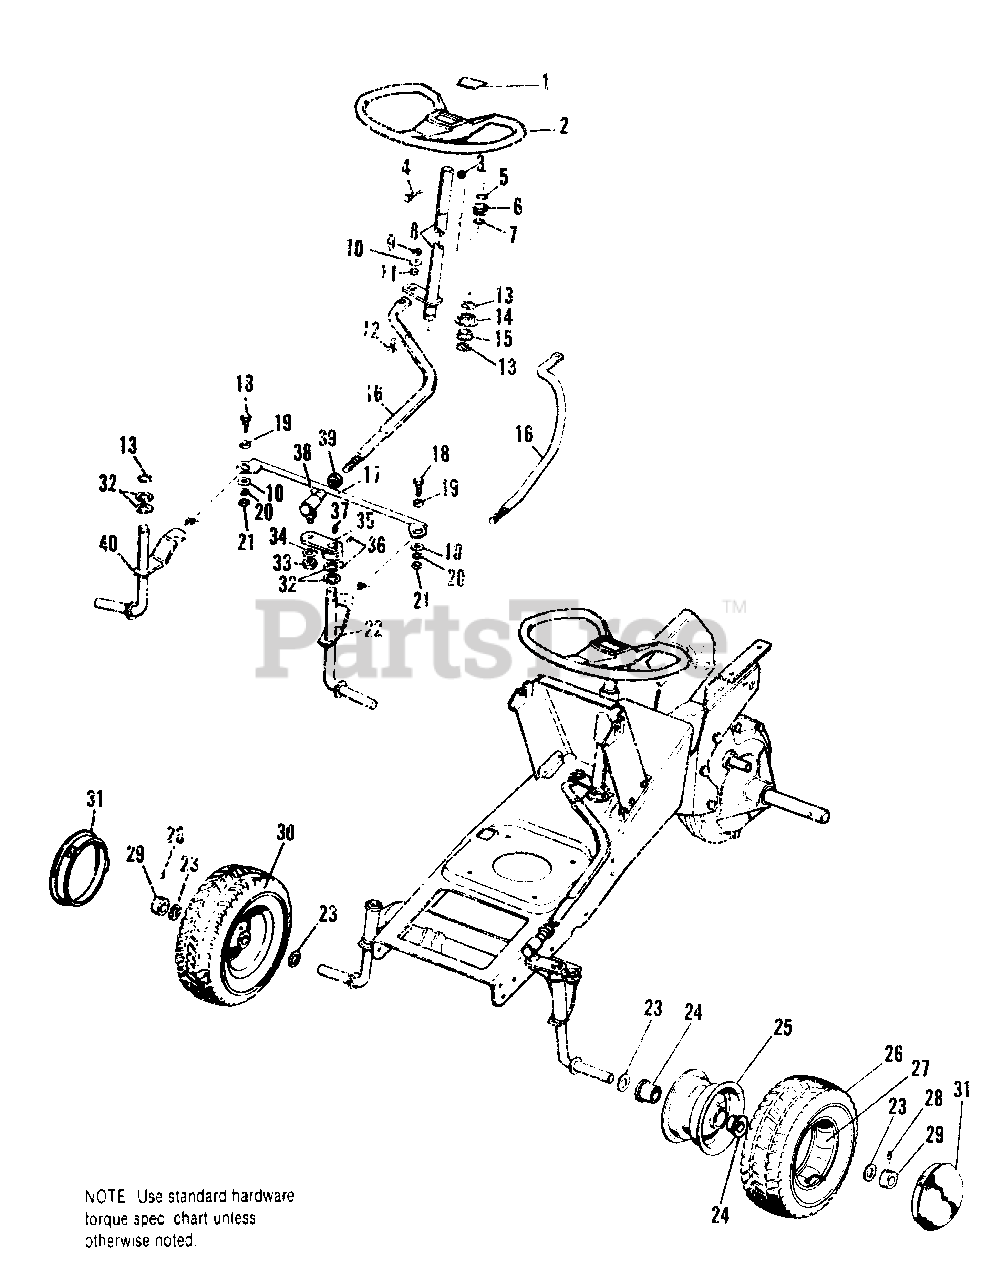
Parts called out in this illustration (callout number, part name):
1	DECAL (990595, 990596, 990796, 990777 Only)
2	WHEEL ASSY., Steering
3	LOCKNUT, Hex, 5/16-18
4	CAPSCREW, Hex Hd., 5/16-18 x 1-1/4
5	RING, Snap (Qty. 2 on 990481 Only)
8	SHAFT, ASSY., Steering 9990595, 990596, 990796, 990777 Only)
8	SHAFT ASSY., Steering
9	LOCKNUT, Hex, 3/8-16
10	WASHER, Plain, 3/8
11	SPACER (990481 Only)
12	CAPSCREW, Hex Hd., 3/8-16 x 1
13	RING, Retainer
14	CUP, Steering Shaft
16	ROD, Tie (990481 & 990485 Only)
17	LINK ASSY., Drag
18	SCREW, Special
20	LOCKWASHER, 3/8
21	NUT, Hex, Full, 3/8-16
22	SPINDLE ASSY., L.H.
24	BEARING (Not used on 990481 Only)
25	WHEEL (Not used on 990481 Only)
26	TIRE (Not used on 990481 Only)
27	TUBE (Not used on 990481 Only)
28	SETSCREW, 5/16-18 x 5/16
29	COLLAR, Set
30	WHEEL & TIRE ASSY.
31	CAP, Hub, Front (990595 & 990596 Only)
31	CAP, Hub, Front (990485 Only)
31	CAP, Hub, Front (990481 Only)
33	NUT, Hex, Full, 1/2-20
34	LOCKWASHER, 1/2
35	LEVER ASSY., Steering
36	SETSCREW, 5/16-18 x 1/2
38	JOINT, Ball
39	LOCKNUT, Hex, Jam, 1/2-20
40	SPINDLE ASSY., R.H.
